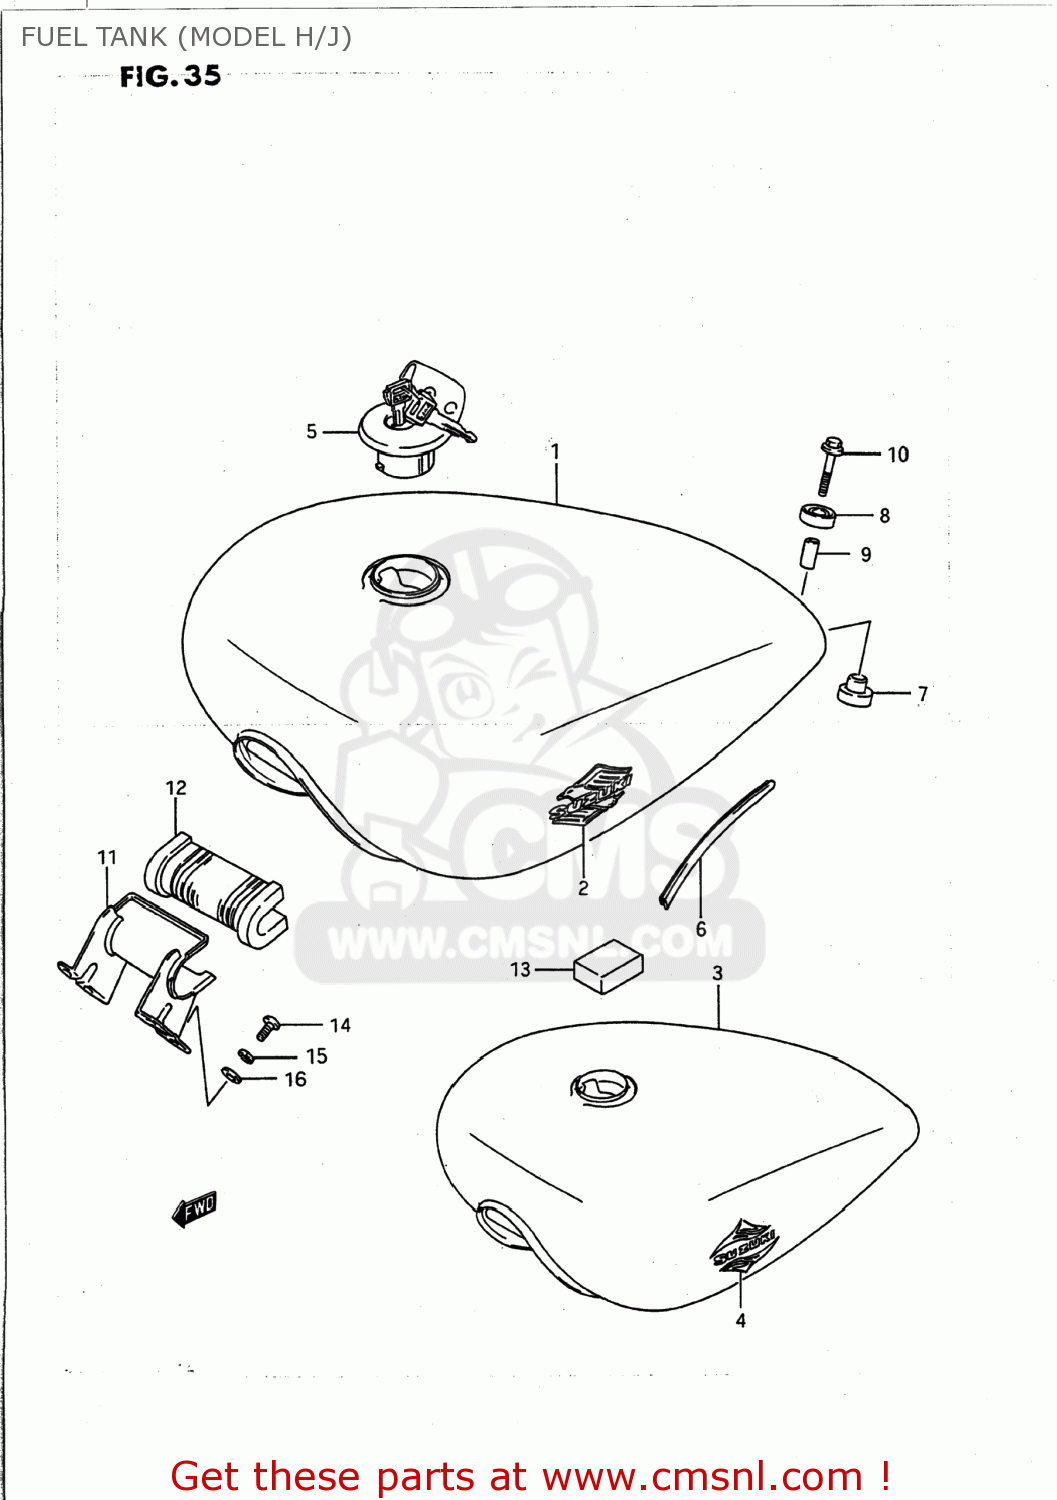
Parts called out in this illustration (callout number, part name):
1	TANK ASSEMBLY,FUEL
2	EMBLEM
3	TANK,FUEL
4	EMBLEM,FUEL TANK
5	CAP SET,FUEL TANK
6	MOLDING,FUEL TANK
7	CUSHION
8	CUSHION
9	SPACER
10	BOLT
11	BRACKET COMP,FUEL TANK
12	CUSHION,FUEL TANK FR
13	CUSHION
14	SCREW
15	WASHER,LOCK
16	WASHER
